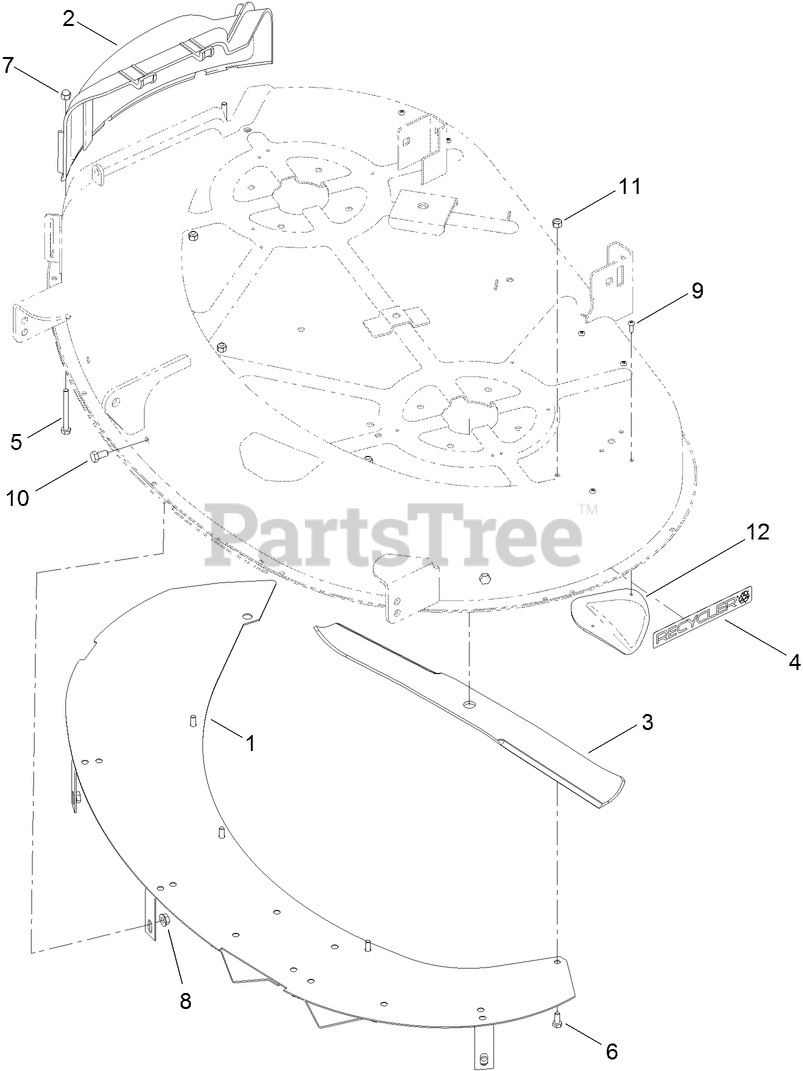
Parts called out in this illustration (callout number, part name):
1	BAFFLE UPPER ASM
2	COVER-DISCHARGE
4	DECAL-RECYCLER
5	SCREW-HH
6	SCREW-HH
7	NUT-CAP
8	NUT-HF
9	SCREW-PPH
10	SCREW-HH
11	NUT-LOCK, NI
12	PLATE-KICKER
